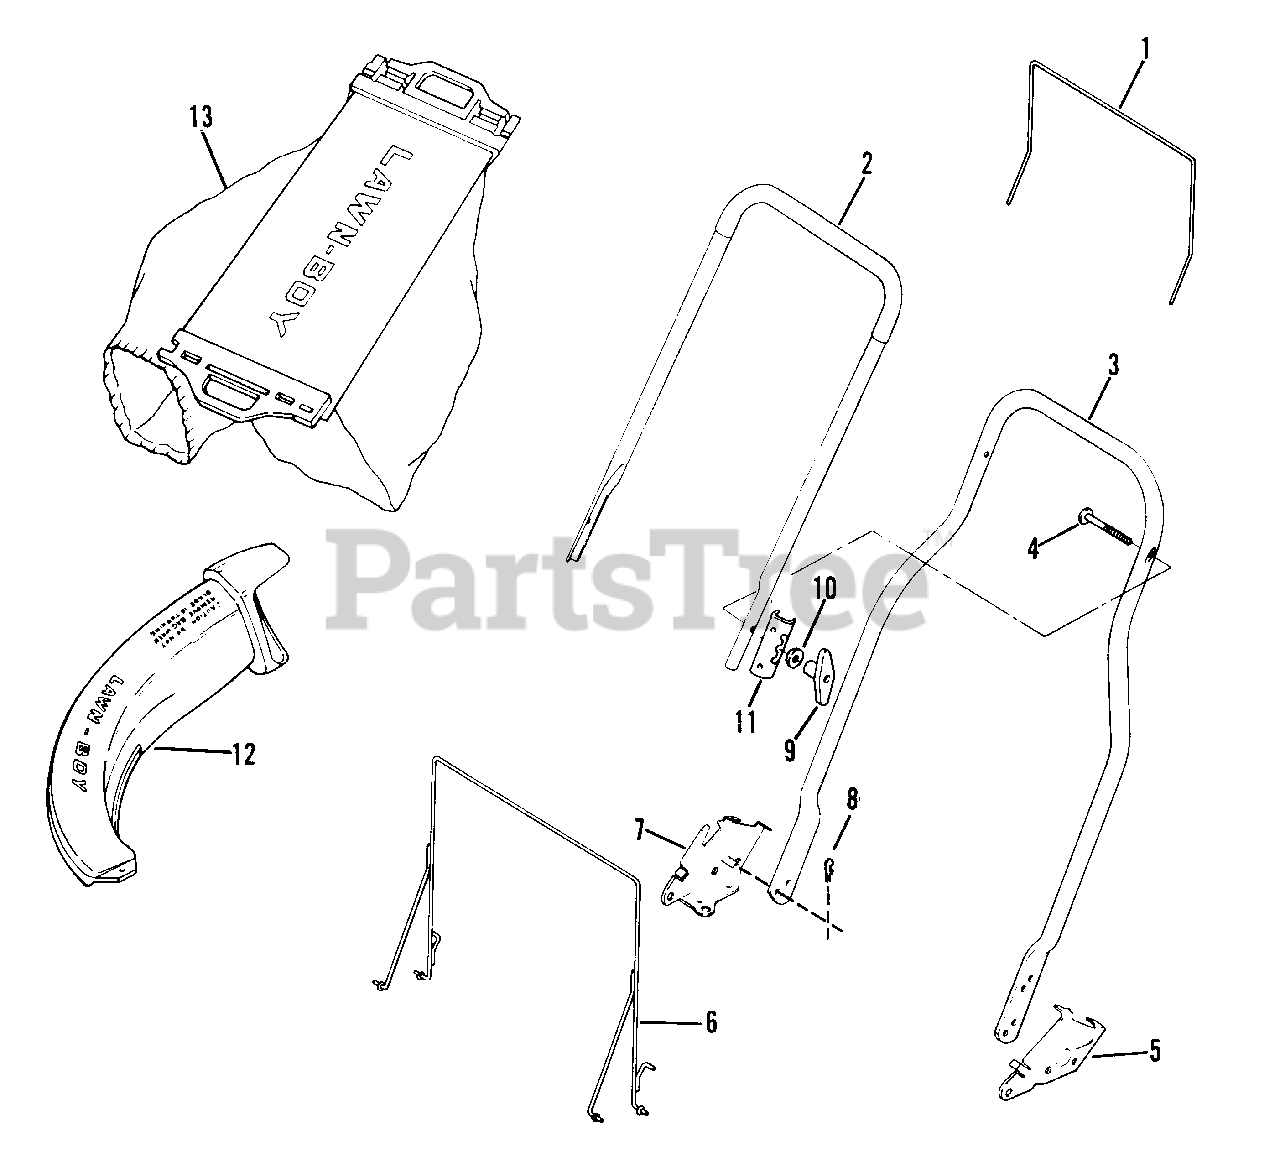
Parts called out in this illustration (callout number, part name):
1	Hanger-Rear
2	Top Handle & Grip Assembly
3	Handle Section-Bottom
4	Screw
5	Handle Bracket-L.H.
6	Hanger Assembly-Front
7	Handle Bracket-R.H.
8	Hair Pin
9	Knob
10	Washer-Curved
11	Bracket-Rear Hanger
12	Chute Assembly
13	Bag & Support Assembly
